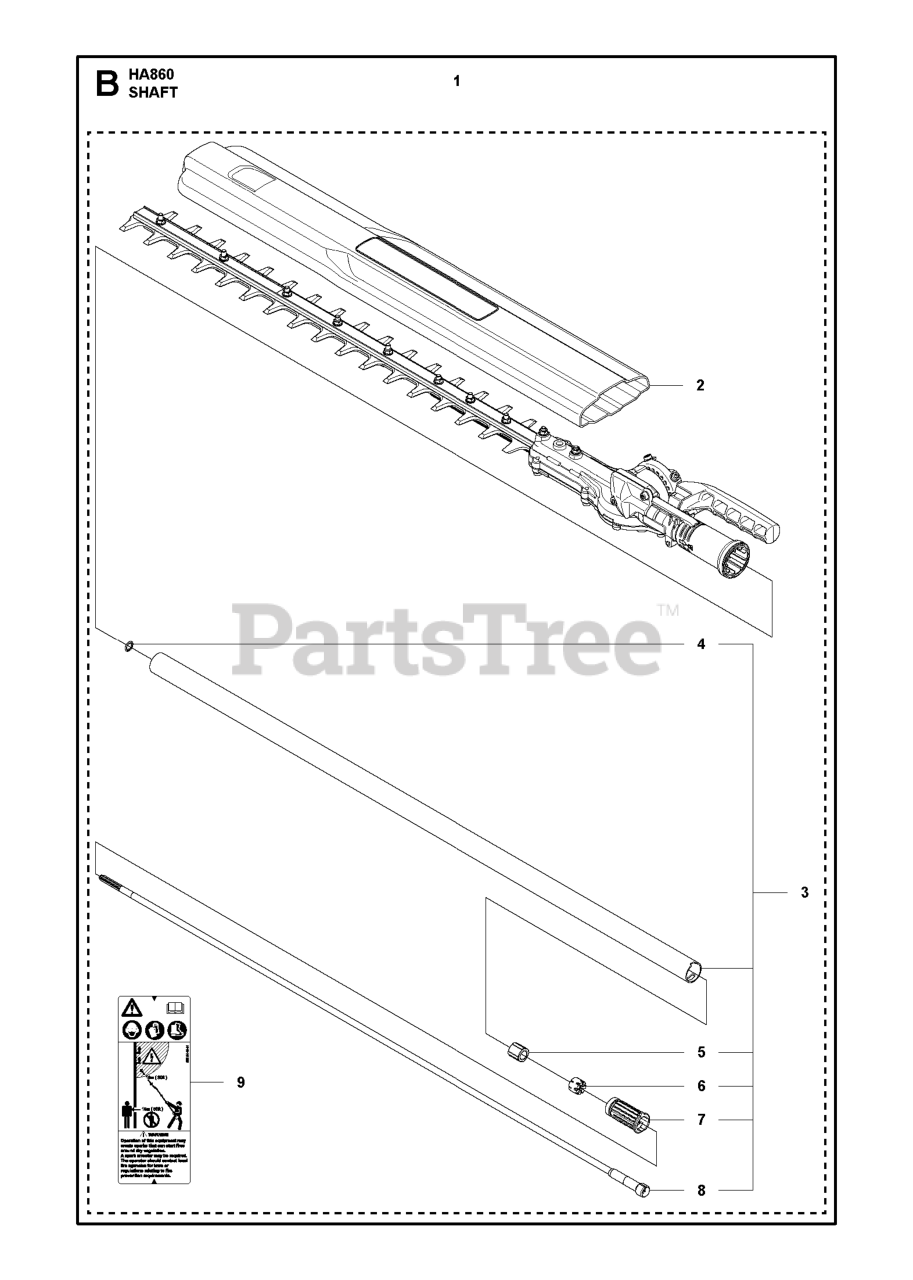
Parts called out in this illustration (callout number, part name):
2	TRANSPORT GUARD HUSQVARNA GRE
3	TUBE COMP LOWER 525LDX
4	WASHER
9	DECAL WARNING SPARK ARRESTOR
